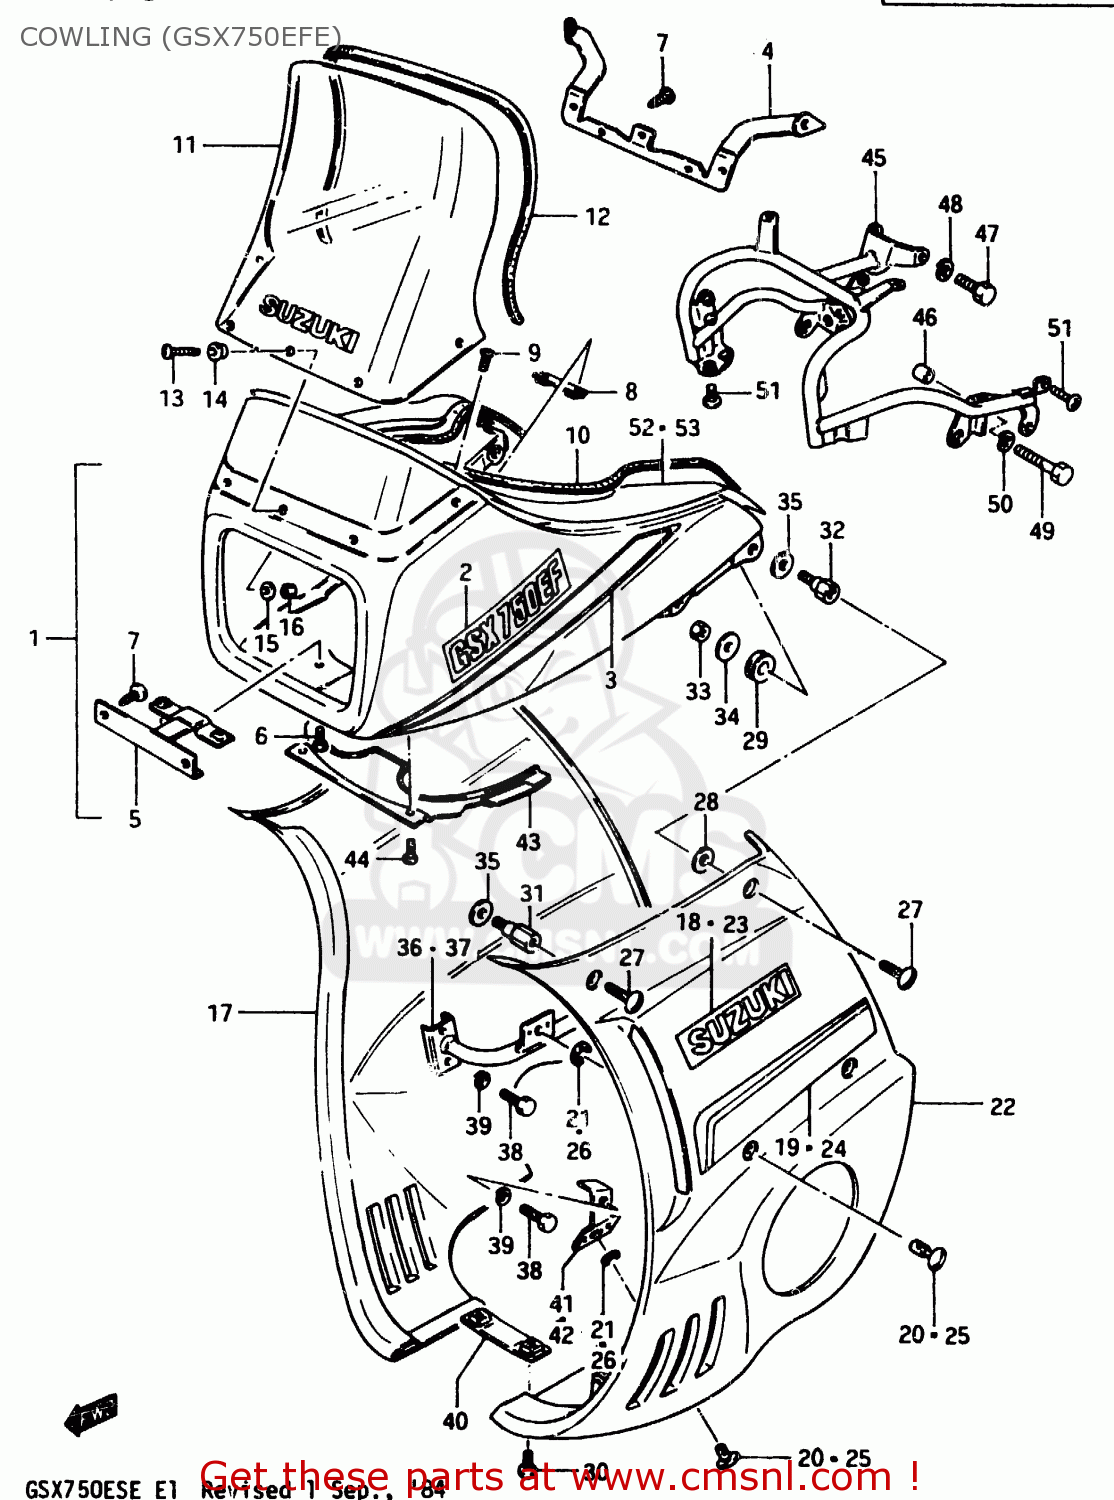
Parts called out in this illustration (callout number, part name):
1	COWLING ASSY (WHITE/RED)
2	EMBLEM
3	TAPE SET
4	BRACE,COWLING,UPPER
5	BRACE,COWLING,LOWER
6	SCREW
7	SCREW
8	BRACKET
9	SCREW
10	MOLDING,FUEL TANK
11	WINDOW
12	MOLDING
13	SCREW
14	CUSHION
15	WASHER
16	NUT ,5MM
17	COVER, RH (WHITE)
18	EMBLEM
19	TAPE SET
20	FASTENER,COWL SIDE COVER
21	E-RING
22	COVER,COWLING
23	EMBLEM
24	TAPE SET
25	FASTENER,COWL SIDE COVER
26	E-RING
27	SCREW,COWLING SIDE COVER
28	NUT
29	CUSHION
30	SCREW 6X12
31	BOSS, FRONT
32	BOSS, REAR
33	NUT
34	WASHER (6.5X24X1.6)
35	WASHER
36	BRACE, RH
37	BRACE, LH
38	BOLT
39	WASHER,LOCK
40	BRACE, FRONT
41	BRACE, RH
42	BRACE, LH
43	COVER,COWLING,LOWER
44	SCREW
45	BRACE,COWLING
46	SPACER,COWLING
47	BOLT
48	LOCK WASHER
49	BOLT, LOWER
50	LOCK WASHER
51	SCREW 6X12
52	TAPE,RIGHT
53	TAPE,LEFT
